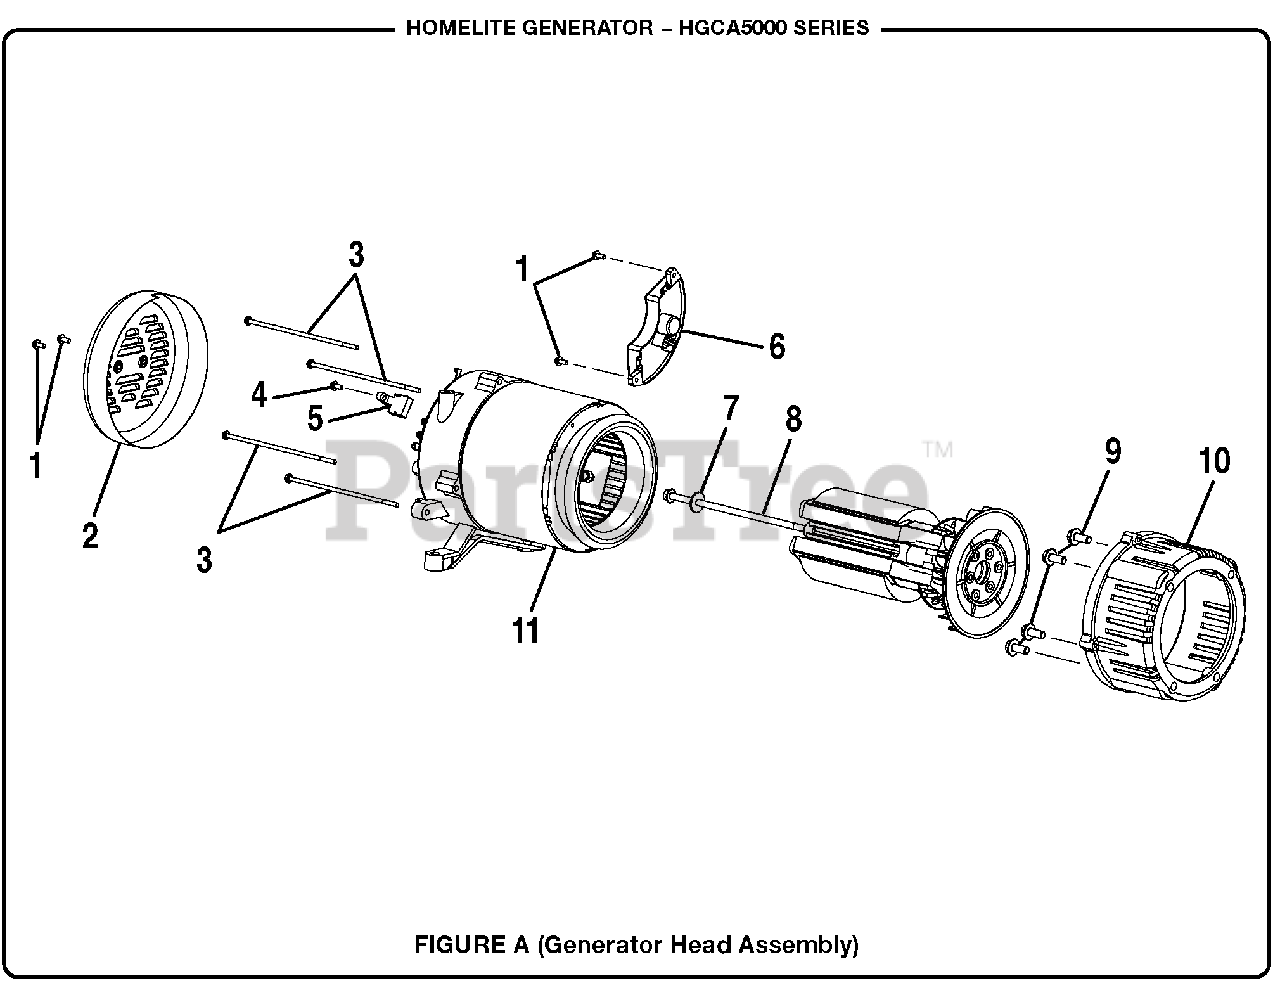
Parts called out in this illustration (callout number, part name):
1	Bolt (M5 x 14 mm)
2	Brush Cover
3	Bolt (M6 x 175 mm)
4	Bolt (M5 x 18 mm, Brush Assembly)
5	Brush Assembly
6	Automatic Voltage Regulator
7	Washer (M5)
8	Bolt (M10 x 270 mm)
9	Bolt (3/8-18 x 1-1/4 in.)
10	Engine Adapter
11	Stator Cover
